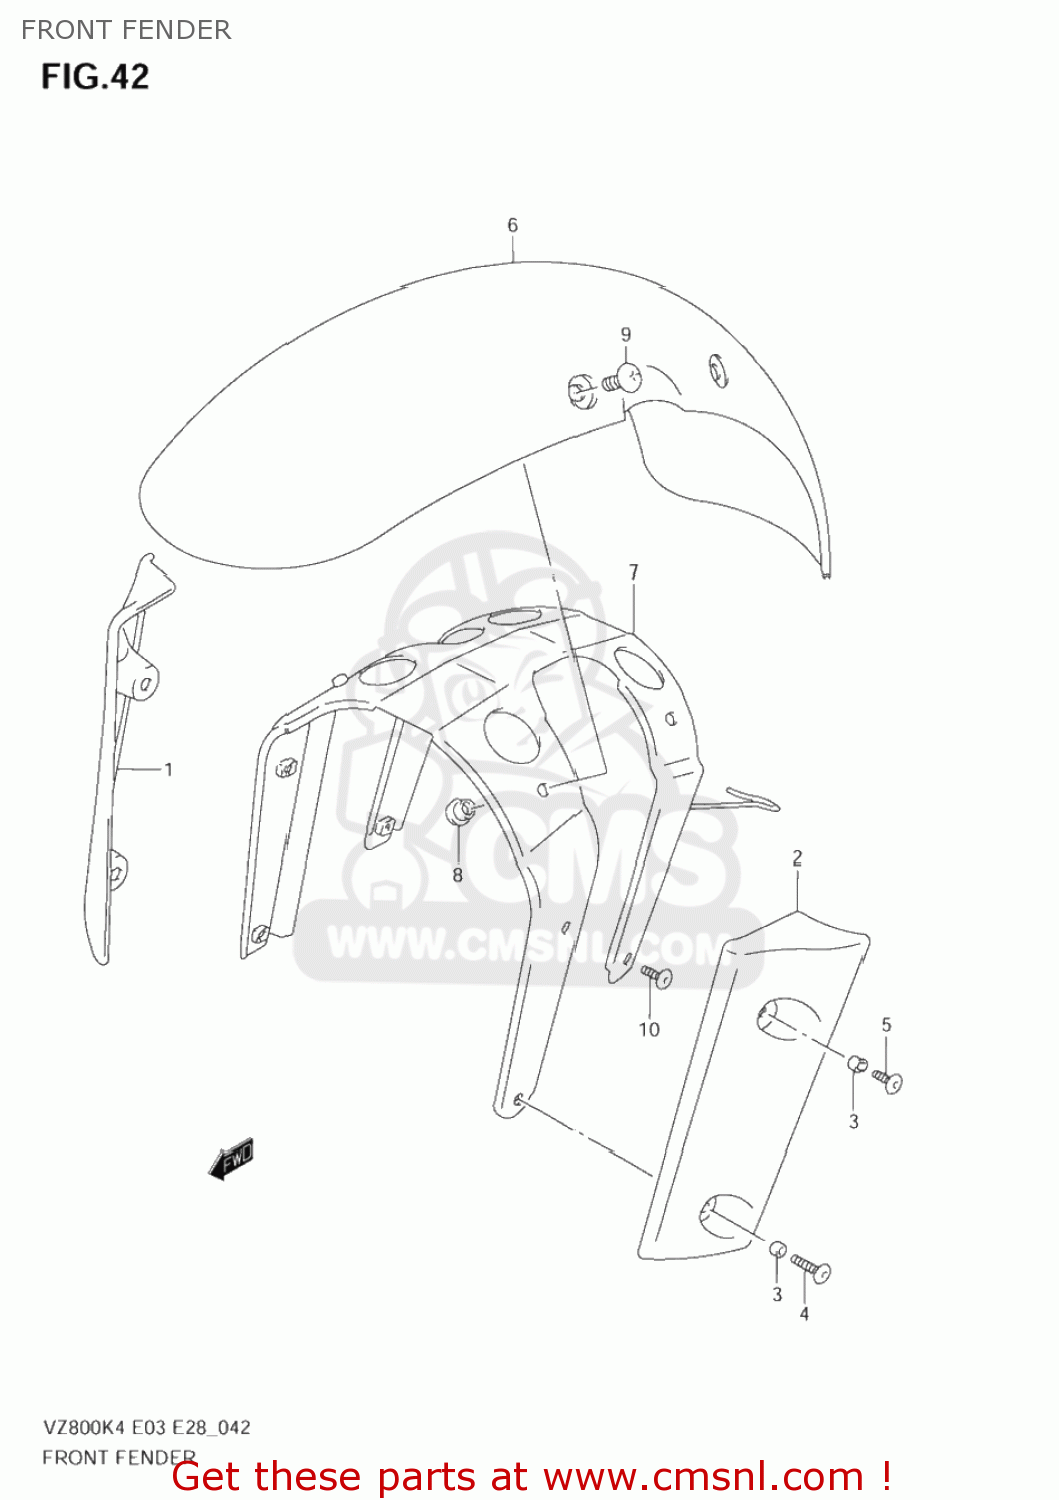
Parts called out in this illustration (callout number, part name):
1	COVER,FR FORK SIDE,R
2	COVER,FR FORK SIDE,L
3	SPACER(6.1X8X3.5)
4	SCREW(6X20)
5	SCREW(6X12)
6	FENDER,FR
7	BRACE,FR FENDER
8	NUT
9	SCREW(6X12)
10	SCREW(6X16)
